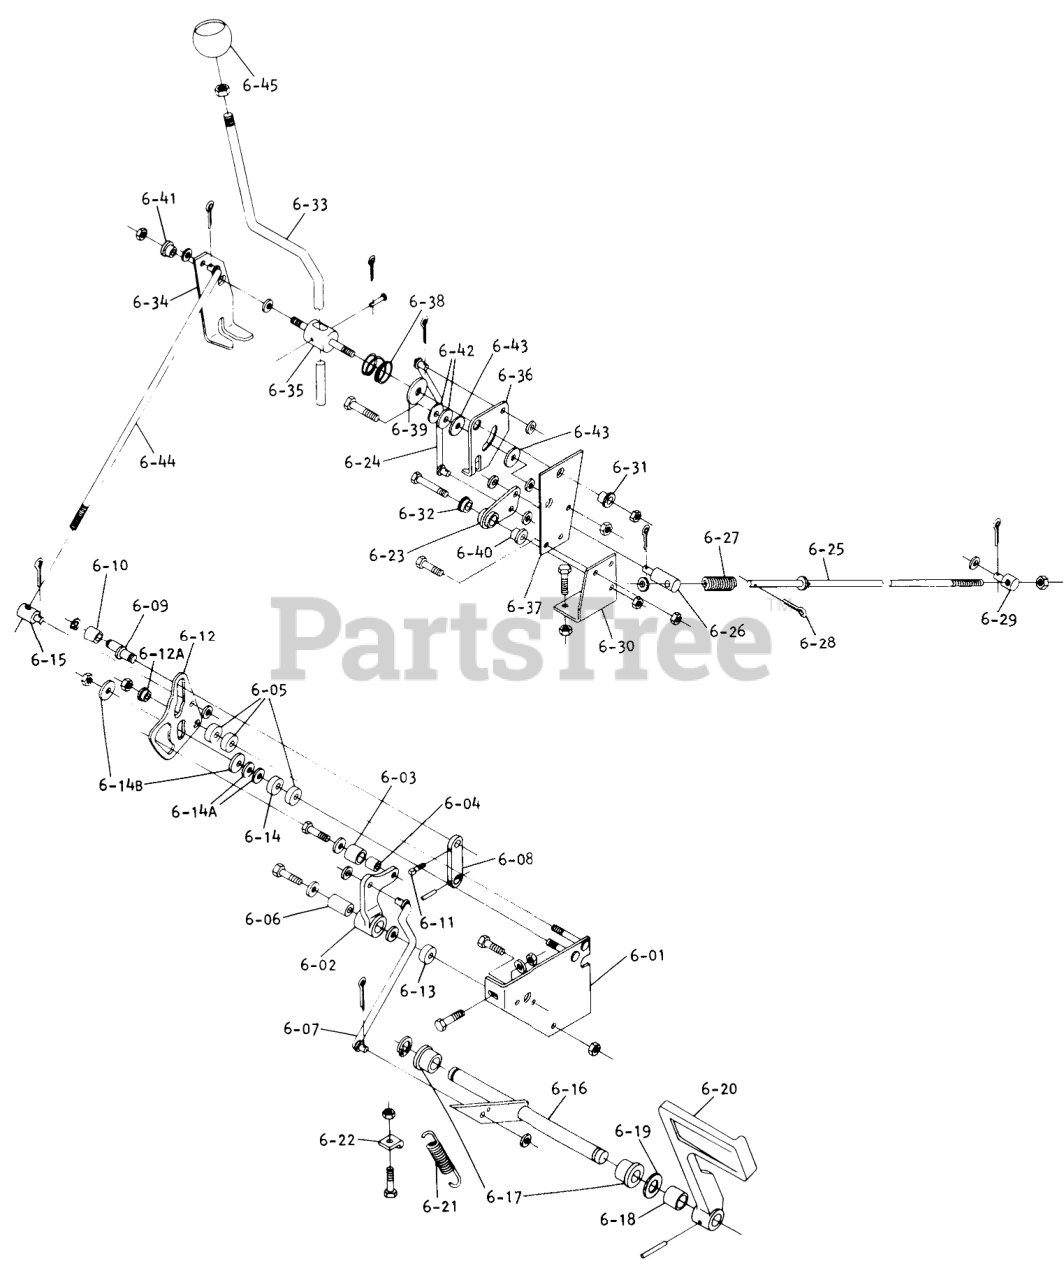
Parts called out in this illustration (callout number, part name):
6-01	Assy-Plate
6-02	Lever-Neutral Return
6-03	BEARING-CAM RETURN
6-04	SPACER
6-05	Spacer
6-06	Spacer
6-07	Neutral Return Rod Assembly
6-08	Arm-Speed Control
6-09	ECCENTRIC-CAM FOLLOW
6-10	Spacer
6-11	Set Screw, 1/4-20 x 1/2 Sq . Hd.
6-12	Cam-Speed Control
6-12A	CAM-SPACER
6-13	Spacer
6-14	SPACER
6-14A	WASHER-SPRING DISC
6-14B	FRICTION WASHER
6-15	Trunnion
6-16	Assy-Shaft
6-17	BEARING
6-18	Spacer
6-19	WASHER
6-20	Brake Pedal
6-21	SPRING-EXTENSION
6-22	CLIP - SPRING
6-23	Lever Assembly
6-24	Rod Assembly
6-25	Washer
6-26	Trunnion
6-27	Spring
6-29	TRUNNION
6-30	Bracket-Support
6-31	FLANGED BUSHING
6-32	CAM-SPACER
6-33	Lever-Speed Control
6-34	Lever-Forward/Reverse
6-35	Pivot Block
6-36	Lever-Park Brake
6-37	Plate-Support
6-38	Washer
6-39	Washer, .406 X 1.5 X .065
6-40	FLANGED BUSHING
6-41	CAM-SPACER
6-42	WASHER-SPRING DISC
6-43	FRICTION WASHER
